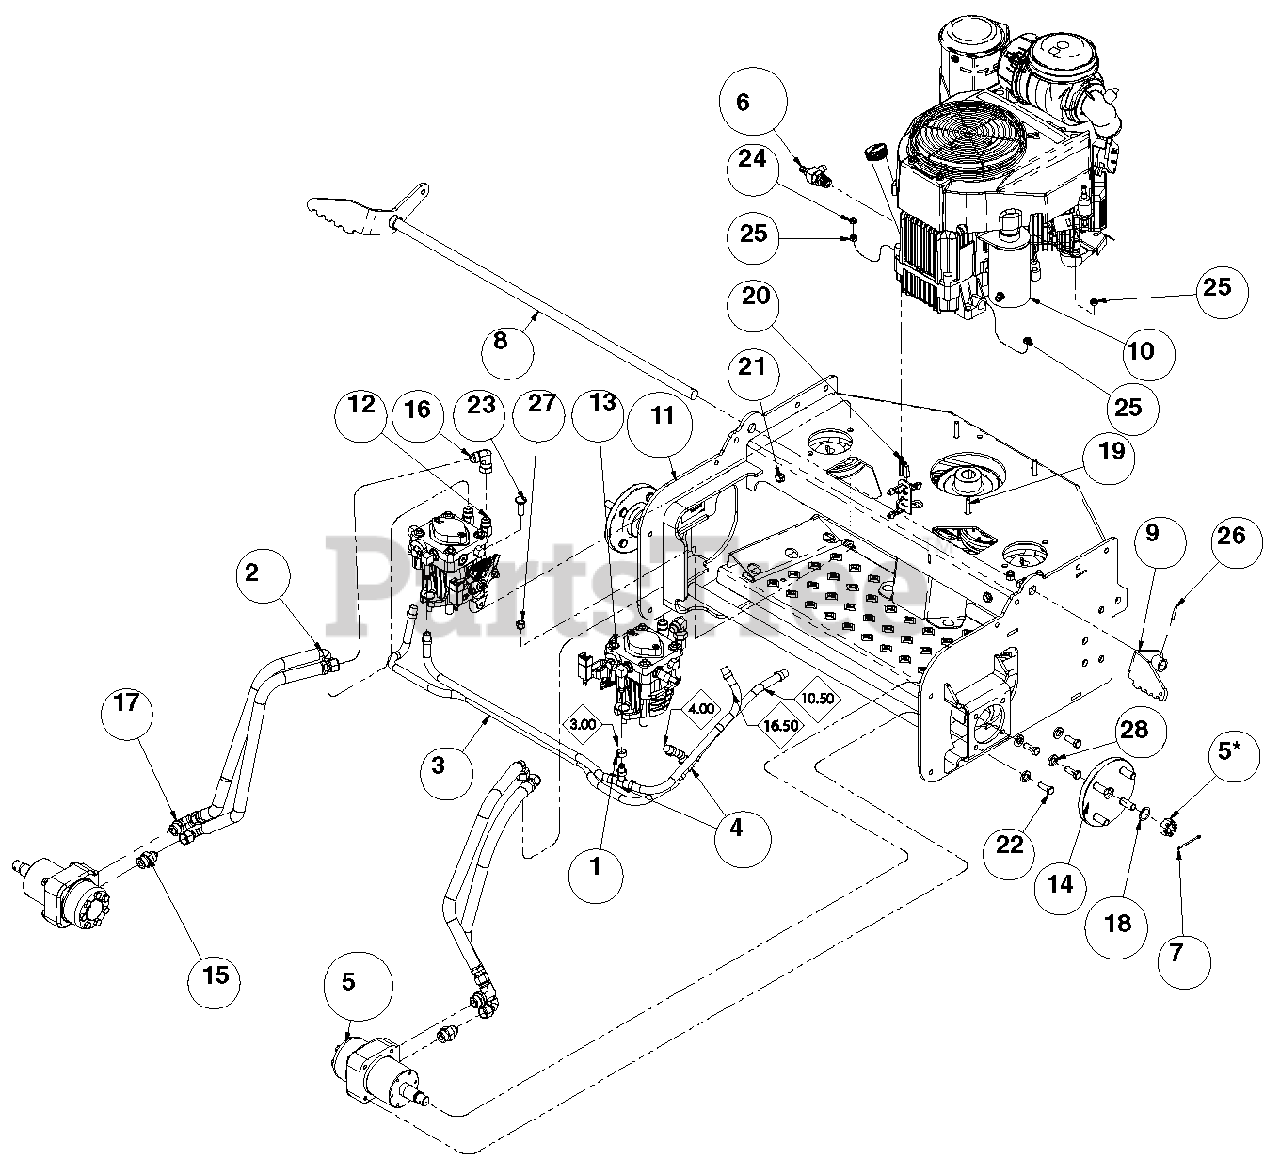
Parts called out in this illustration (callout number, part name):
1	Clamp, Hose - 1/2" Pinch
2	Hose Assembly
3	Hose, 3/8 SAE 30R7 Fuel & Oil
4	Fitting, TUN 3/8 Hose
5	Motor, Wheel HGM-12P-7172 (*Includes Castle Nut, tighten to 163 N•m (120 lbf-ft))
6	Fitting, Oil Drain
7	Pin, Cot .125 x 2.00 Extp Y
8	Weldment, Brake Shaft
9	Weldment, RH Brake Arm
10	Engine, Kawasaki 19HP FH580V (994101, 105)
11	Weldment, Deck Frame w/Decals
12	Assembly, HYD Pump (See Pump Components on page 14.)
13	Assembly, HYD Pump (See Pump Components on page 14.)
14	Assembly, Rear Wheel Hub
15	Fitting, ADP 3/4-16FJIC x 7/8-14MOR
16	Fitting, ADP MJIC-FSWJIC 6500-08-08
17	Fitting, ADP JIC-ORB 2062-10-8S
18	Bushing, Mach., .75 x 1.25 x .048
19	Bolt, .3125-18 x 1.50 Hex 5 Y
20	Bolt, .3125-18 x 1.75 Hex 5 Y
21	Bolt, .375-16 x 1.00 FGH 8 Y
22	Bolt, .375-16 x 1.00 Hex 5 Y
23	Bolt, .375-16 x 1.25 CRG 5 Y
24	Nut, .3125-18 JAM GR5 Y
25	Locknut, .3125-18 Nyloc Y
26	Pin, Roll .156 x 1.00
27	Locknut, .375-16 Nyloc Y
28	Washers, .375 Medium Spring Lock
